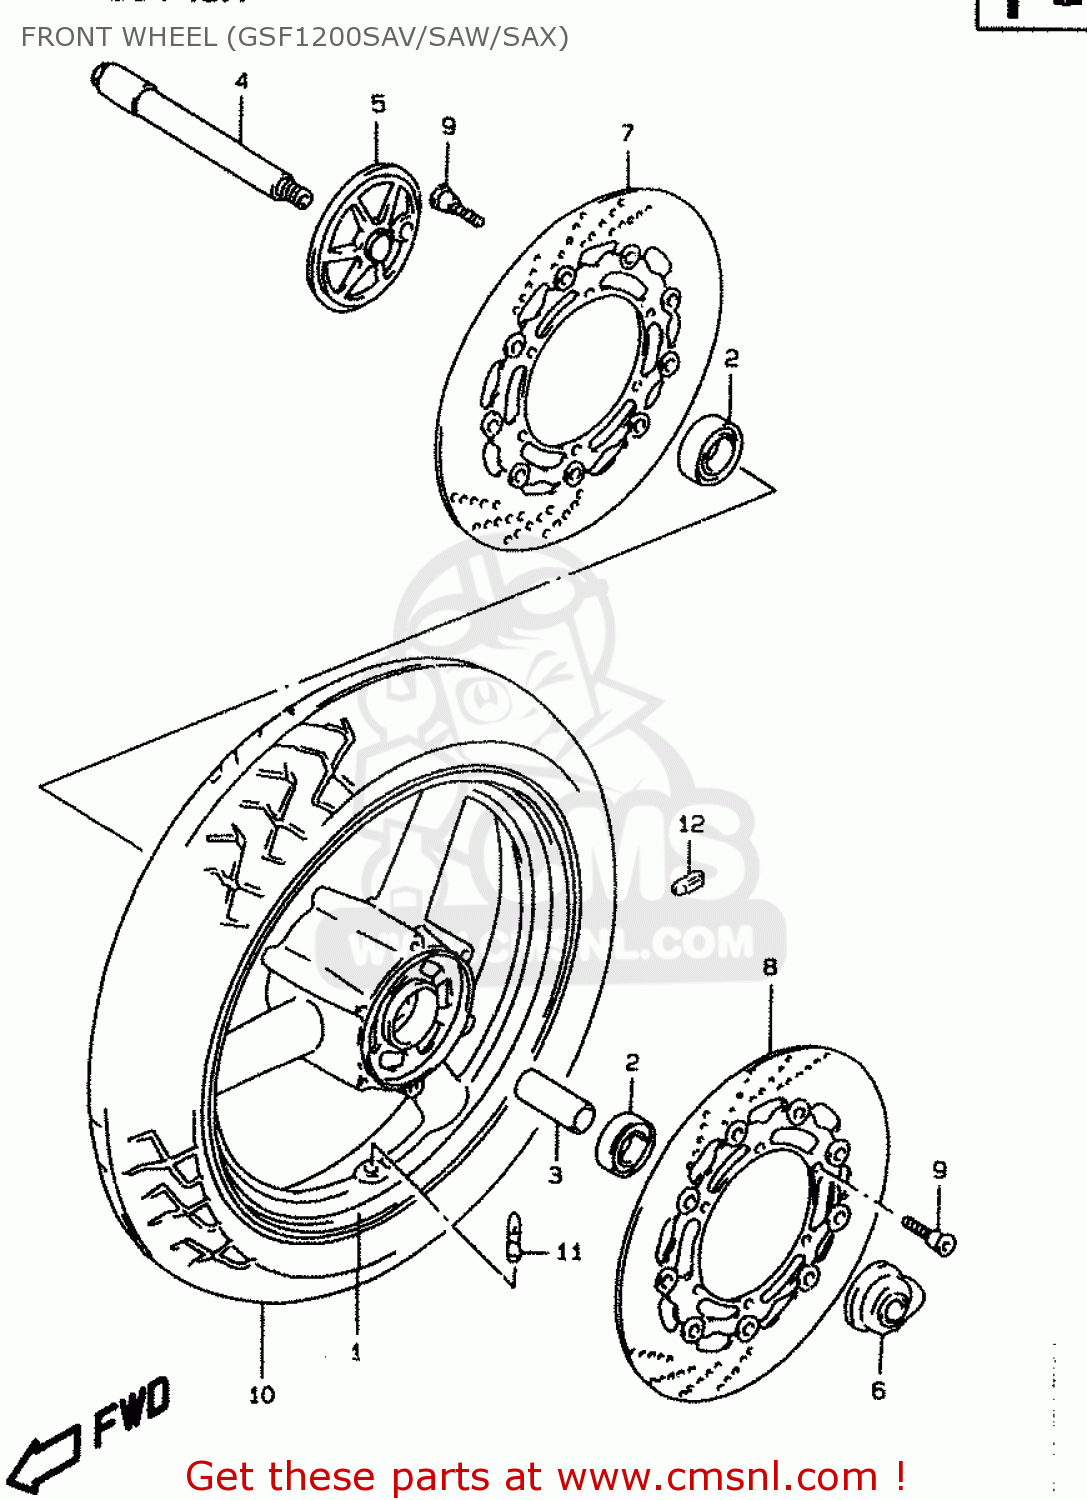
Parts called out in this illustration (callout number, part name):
1	WHEEL SET,FRONT (17XMT3)
2	BEARING
3	SPACER(20.8X27.2X74)
4	AXLE,FR
5	PANEL,SPEED SENSOR FR
6	BOX ASSY,SPEEDOMETER GEAR
7	DISC,FR BRAKE,R
8	DISC,FR BRAKE,L
9	BOLT 8X33
10	TIRE,FRONT 120/70 ZR17
11	VALVE ASSY,WHEEL RIM(TR412)
12	BALANCER,WHEEL (10G)
